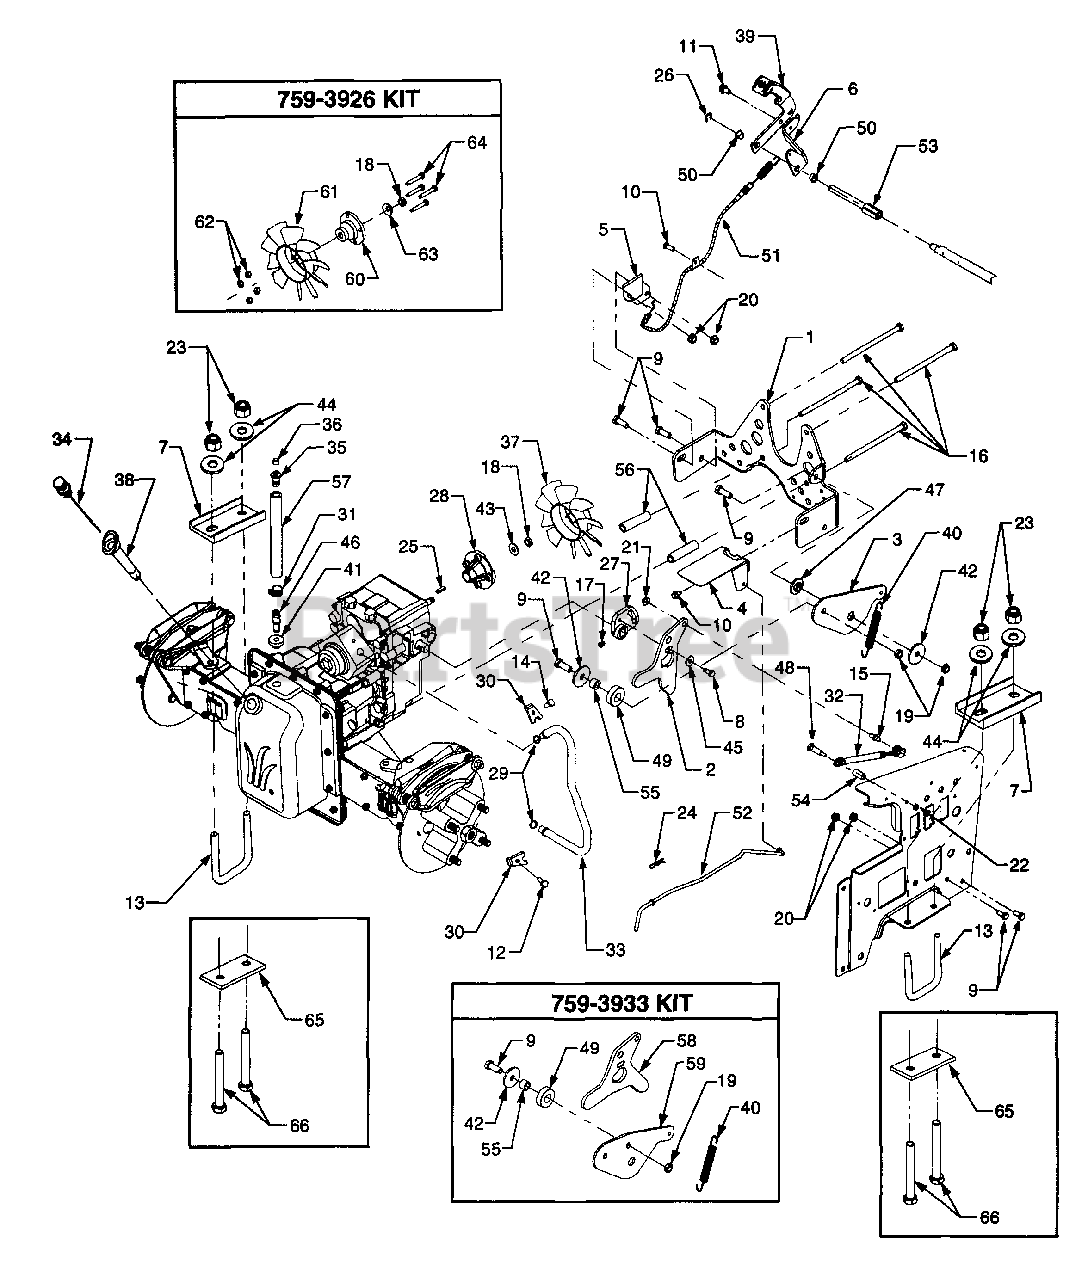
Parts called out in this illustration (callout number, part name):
1	Bracket, Torque
2	Plate, Hydro Neutral Return
3	Link, Neutral Return Bearing
4	Spring Plate, Hydro Bypass
5	Bracket, Cable Retainer
6	Bracket, Pedal Brace
7	Plate, Reinforcement
8	Screw, Hex Cap, 1/4-20 x .625 GR5 Lock
9	Screw, Hex Cap, 3/8-16 x 1.0 GR5
10	Screw, Hex Wash. Hd. Tapp 1/4-20 x .5
11	Screw, Hex Wash. Hd. Tapp 3/8-16 x .75
12	Screw, Hex Wash. Hd. Tapp 1/4-20 x .75
13	Bolt, U-Style
14	Screw, Hex Cap 1/4-20 x .75 GR5
15	Ball Screw, 5/16-18 x .56
16	Screw, Hex Cap 5/16-18 x 5.5 GR5 Lock
16	Screw, Hex Wash. Hd. Tapp 5/16-18 x 5.5 GR5
17	Screw, Set, 5/16 x .5
18	Nut, Hex Ctr. Lock Jam, 3/8-24
19	Nut, Hex Ctr. Lock Jam, 3/8-16
20	Nut, Hex Flange Lock, 3/8-16
21	Nut, Hex Flange Lock, 5/16-18
22	Nut, Hex, 1/4-20
23	Nut, Hex Insert Lock, 1/2-20
24	Pin, Internal Cotter
25	Key, 3/16 x .75
26	E-Ring, .5 Dia. Shaft
27	Arm, Hydro
28	Adapter, Pump
29	O-Ring, 426 ID x .566 OD x .070
30	Clamp, Tube
31	Clamp, Hose
32	Cylinder, Damper
33	Tube, Hydro Pickup
34	Dipstick, Transmission
35	Plastic Vent
37	Fan, Pump
38	Holder, Dipstick
39	Pedal, Diff Lock
40	Spring, Extension
42	Washer, Flat, .390 x 1.5 x .1
43	Washer, Flat
44	Washer, Flat, .531 x 1.062 x .134
45	Washer, Flat, .26 x .72 x .06
46	Fitting, Tube
47	Spacer, Shoulder
48	Shoulder Bolt
49	Bearing, Ball
50	Bearing, Nylon Flange
51	Cable, Diff Lock
52	Rod, Pump Bypass
53	Shaft, Diff Lock
54	Spacer, .375 x .5 x 1.02
55	Spacer, .375 x .624 x .445
56	Spacer, Hydro, .3223 x .60 x 2.44
57	Fuel Line
58	Plate, Hydro Neutral Return
59	Link, Neutral Return Bearing
60	Adapter, Pump
61	Fan, Pump
62	Nut, Fan, 1/4-20
63	Washer, Bell, .401 x .87 x .063
64	Screw, Hex Cap Lock 1/4-20 x 1.62
